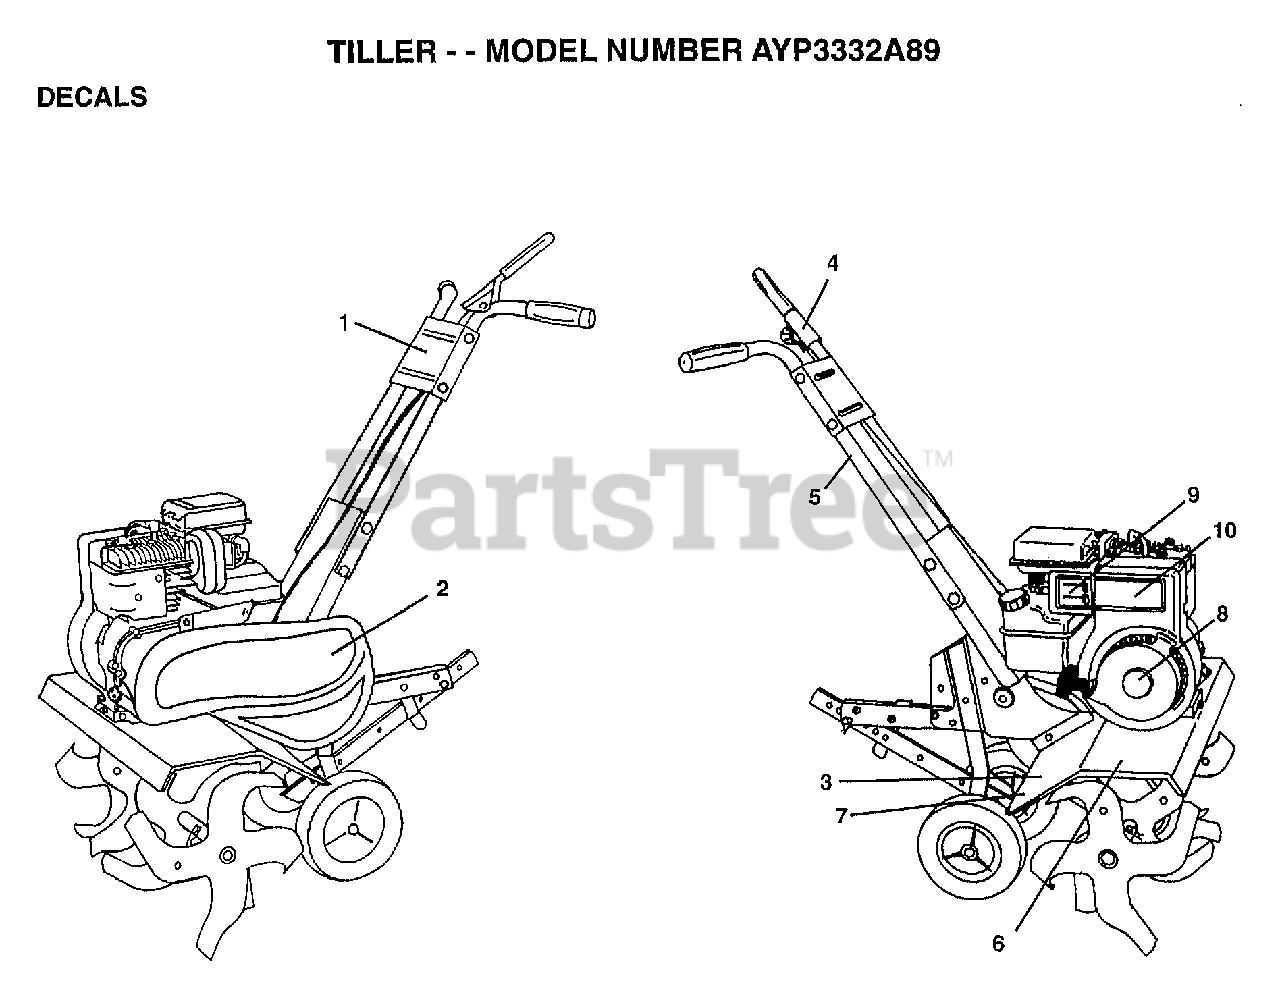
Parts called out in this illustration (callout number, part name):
1	DECAL PANEL CONT
2	DECAL, LOGO
4	DECAL TI
5	DECAL TI
6	DECAL.TINE.SHIELD
7	DECAL TI
9	DECAL.SPEED.CONTROL
